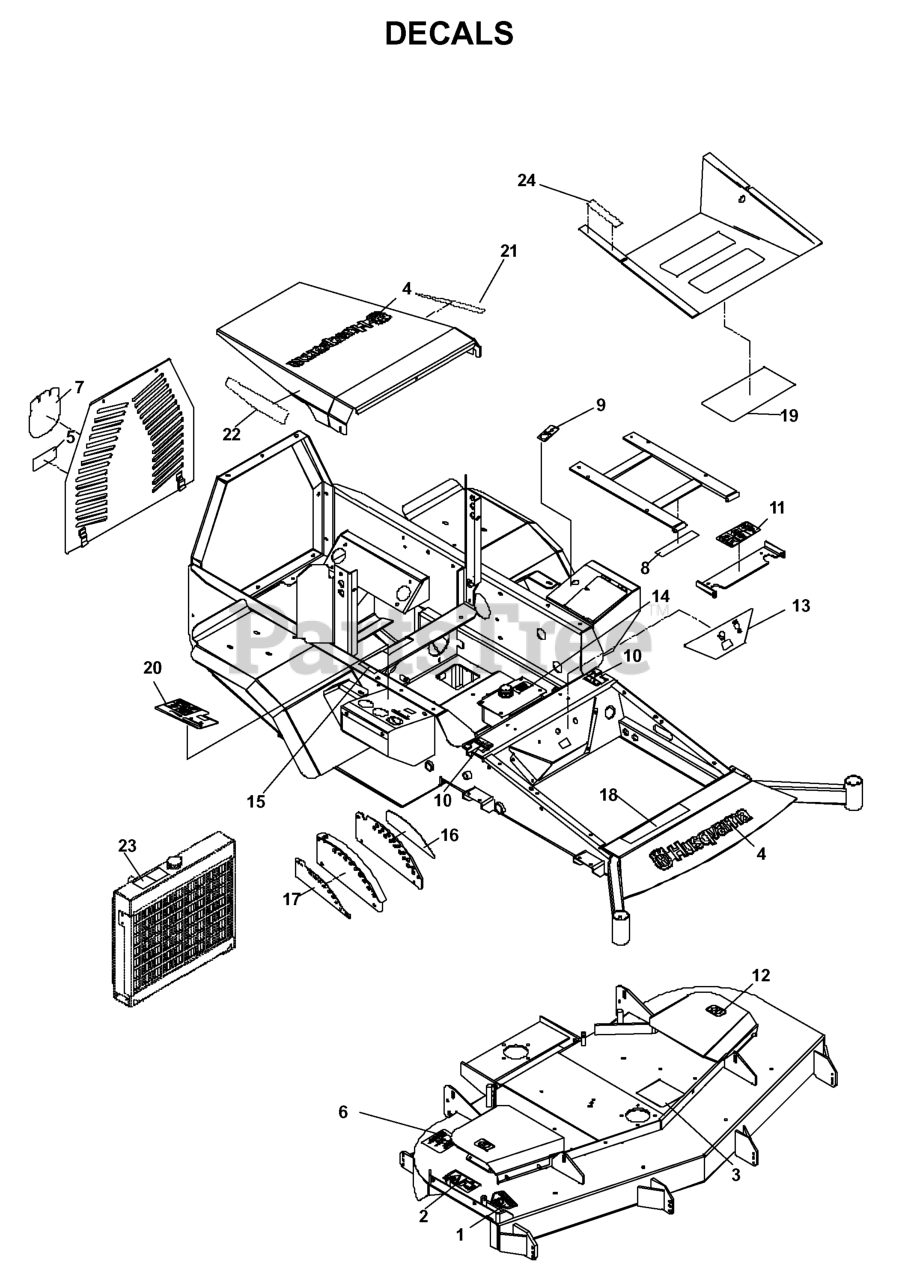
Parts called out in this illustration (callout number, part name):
1	DECAL, CPSC
2	DECAL, EURO SEVERING
3	DECAL, BELT ROUTING
4	DECAL, HUSQVARNA 17.5"
5	DECAL, BELT DRIVE
6	DECAL, ANTI SCALP
7	DECAL, LGE CROWN 7X6"
8	EURO DECAL-BATTERY WARNIN6
9	DECAL, 12V
10	DECAL, MOTION CONTROL
11	DECAL, EURO WARNING
12	DECAL, NO STEP
13	DECAL, FRONT CONSOLE
14	DECAL, MOBIL 1
15	FUEL VALVE DECAL
18	DECAL, MODEL BZE6127D
19	DECAL, SERVICE
20	DECAL, RT CONSOLE
21	DECAL, 34 TURBO LH
22	DECAL, 34 TURBO RH
23	DECAL, HOT
539100128	DECAL, EXHAUST
539106255	DECAL BZE7234D
